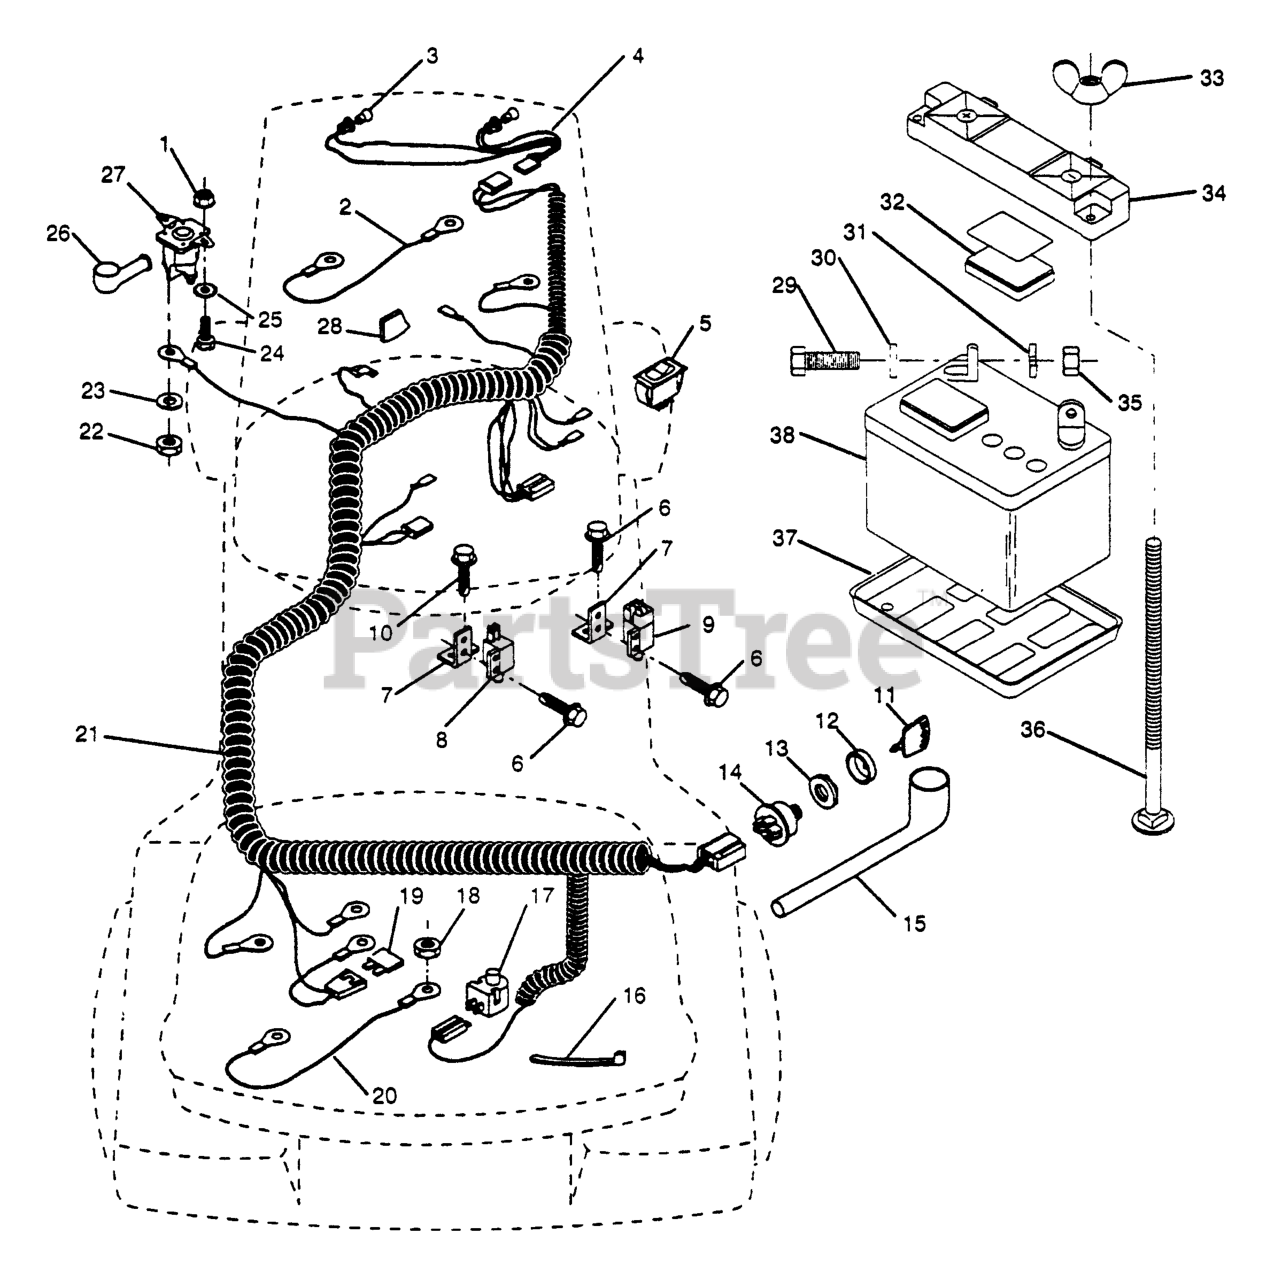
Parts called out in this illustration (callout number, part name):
1	NUT
3	BULB-LIGHT T
4	HARNESS LIGHT SOC
7	BRACKET LT
8	SWITCH-INTER. GT
9	SWITCH INTERLOCKT
10	Screw, Hex Wsh. Tap #10-16 x 1/2
11	KEY.MOLDED.GENERIC
12	COVER KEY IGNITIO
13	NUT IGNITION
14	SWITCH
15	COVER IGNITION SW
16	TIE GUIDE
17	RP.SWITCH.PLUNGER.NC.GRAY
18	NUT
20	CABLE ASSY LT
21	HARNESS IGNITION
22	NUT
23	LOCKWASHER
24	BOLT
25	Washer. Lock Ext. Tooth 1/4
26	TERMINAL COVER
27	SOLENOID KIT
28	STOP PLASTIC
29	BOLT.HEX.1/4.X.3/4.DICHROMATE
30	WASHER
31	LOCKWASHER
32	CAP BATTERY NLA
33	WING NUT
34	TERMINAL GRD YTV
35	NUT
37	BATTERY TRAY T
38	BATTERY
